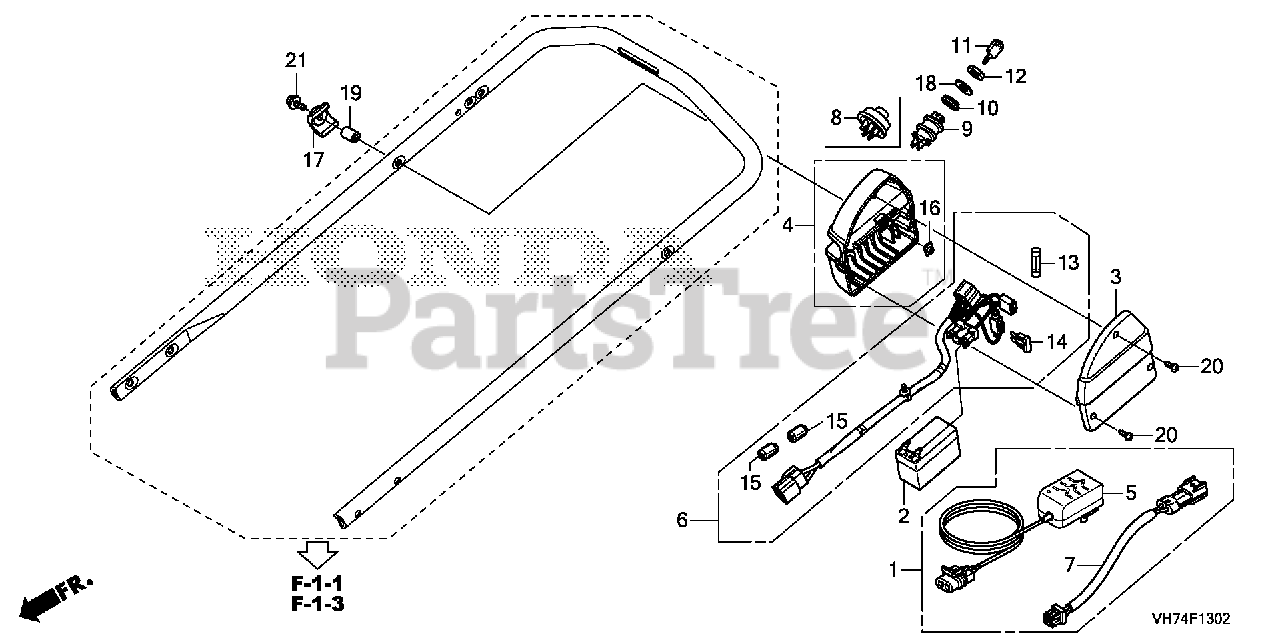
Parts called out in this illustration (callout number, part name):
1	CHARGER KIT, HARNESS
1	CHARGER ASSY., BATTERY (FLOAT-CHG)
2	BATTERY ASSY. (MSDS)
3	COVER, BATTERY
4	BOX, BATTERY
5	CHARGER ASSY., BATTERY (FLOAT-CHG)
6	HARNESS ASSY., MAIN
7	HARNESS ASSY., CHARGER
8	SWITCH ASSY., COMBINATION
10	BASE, MOMENT SWITCH
12	NUT, SWITCH
13	FUSE A (30A) (SLO-BLO)
14	FUSE, BLADE (3A)
15	FILTER, SUB NOISE (AC)
16	NUT, SPECIAL (6X7)
17	WASHER, FRAME JOINT
18	WASHER, SWITCH
19	COLLAR, BATTERY MOUNTING
20	SCREW, TAPPING (4X16)
21	BOLT, FLANGE (6X35)
